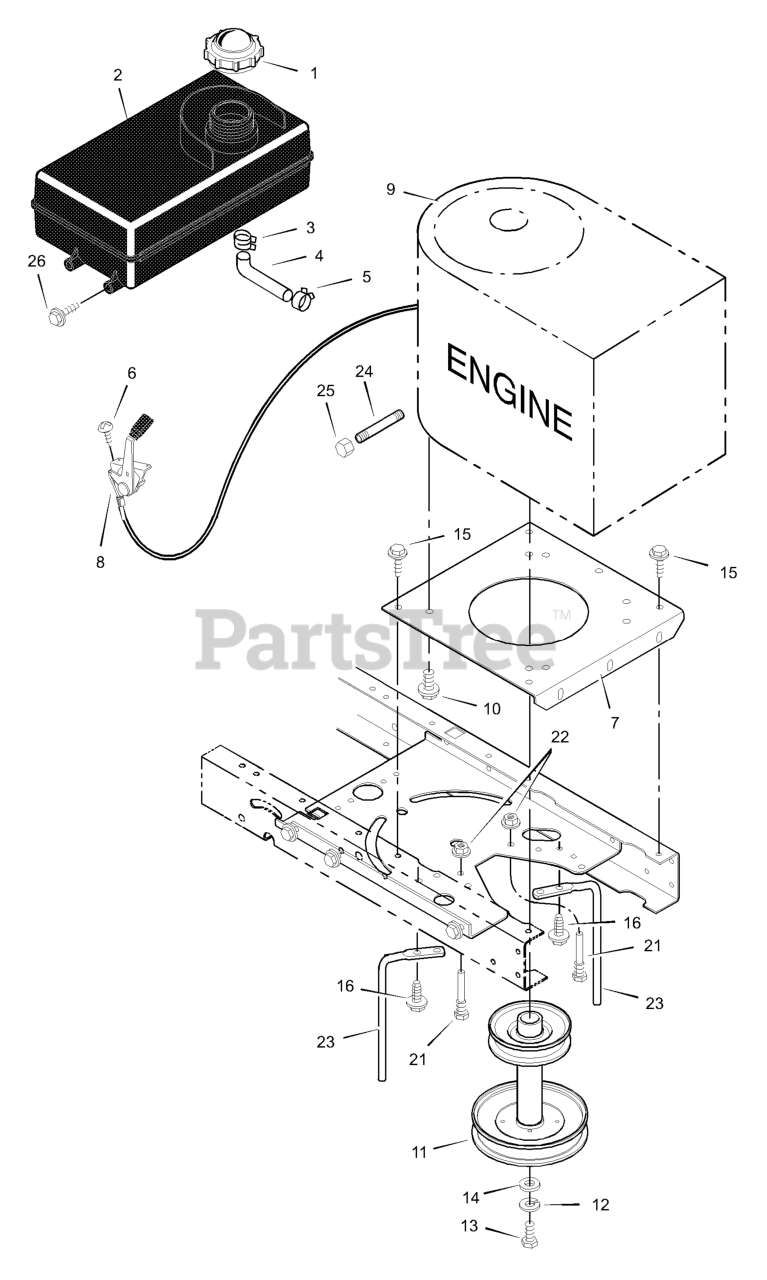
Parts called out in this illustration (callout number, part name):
1	Fuel Cap
2	TANK, Fuel 1.4 Gal.
3	Hose Clamp
4	Fuel Line
5	Hose Clamp
7	Plate, Engine
8	Throttle Control
9	Engine *
10	Bolt, Engine Mount
11	Stack Pulley Assembly
12	Lockwasher
13	Bolt, Hex
16	Screw
21	Guide, Belt
22	Nut, Flange
23	Guide, "L" Belt
24	Pipe, Oil Drain
25	Cap, Oil Drain
